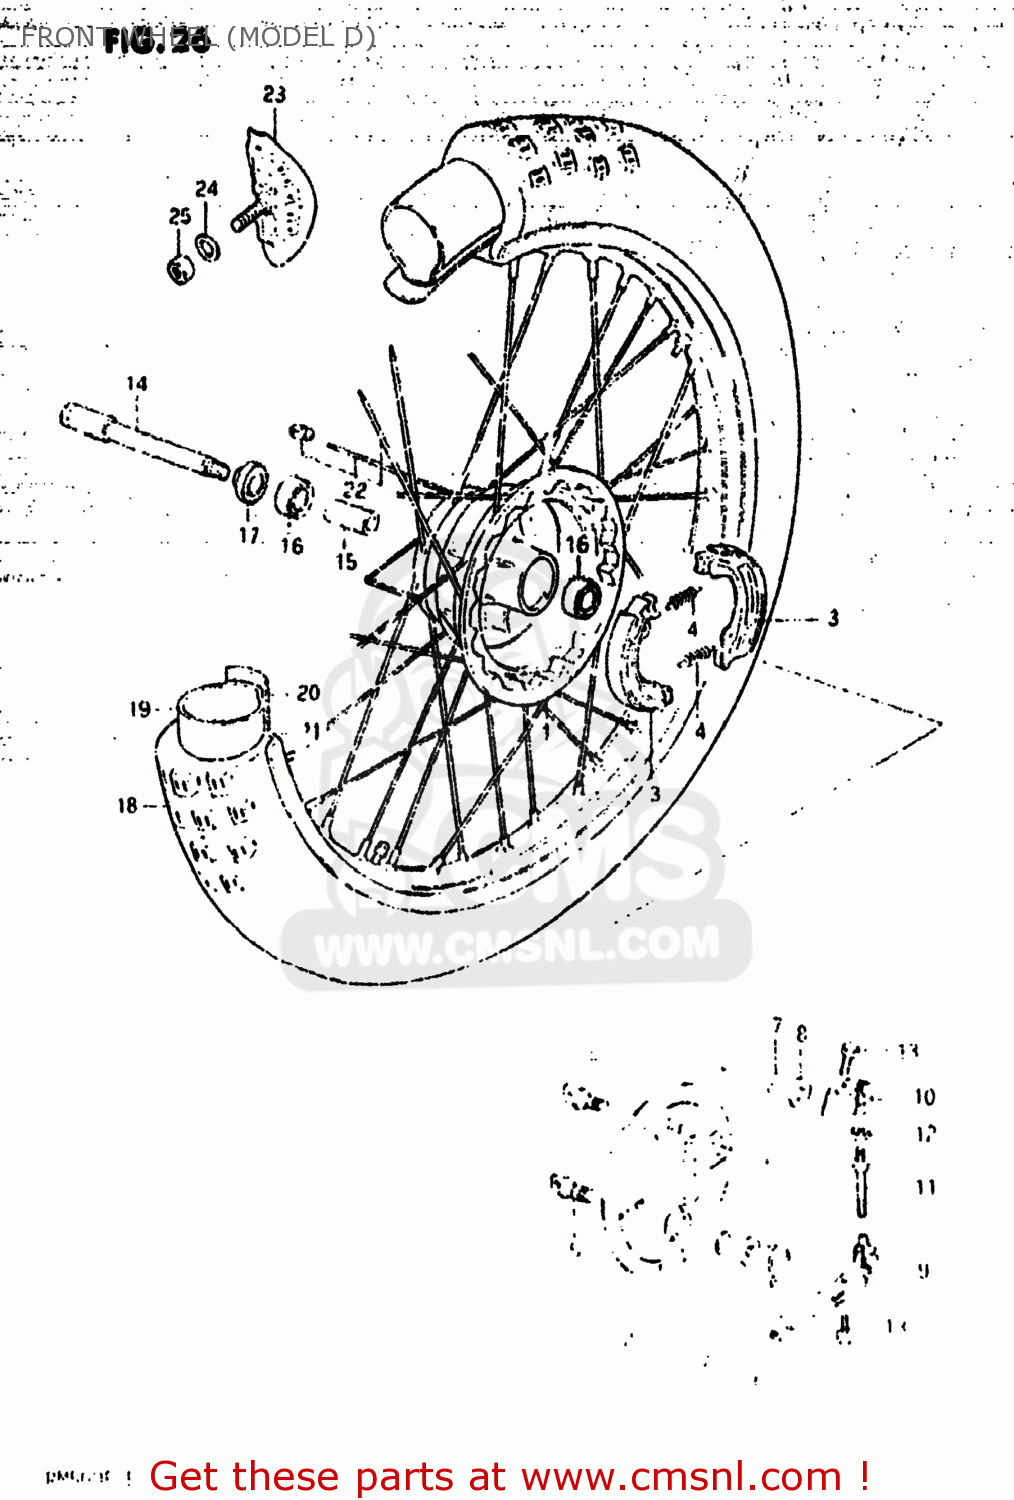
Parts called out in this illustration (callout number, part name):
1	HUB,FRONT
2	PANEL,FRONT HUB
3	SHOE,BRAKE (MCA)
4	SPRING
5	CAM,FRONT BRAKE
6	SPRING
7	O-RING (D:2 ID13.8)
8	WASHER (14.2X22X1)
9	LEVER, BRAKE CAM
10	LEVER ASSY, BRAKE CAM, NO.2
11	ROD,BRAKE CAM LEVER CONNECTION
12	NUT 6MM
13	BOLT
14	AXLE,FRONT
15	SPACER,FRONT HUB BEARING
16	BALL BEARING 15X35X11
17	SPACER,FRONT AXLE,RIGHT
18	TIRE,FRONT
19	TUBE,INNER
20	PROTECTOR,WHEEL,INNER
21	RIM,FRONT WHEEL
22	SPOKE SET,FRONT
23	STOPPER,BEAD
24	WASHER
25	NUT 8MM
